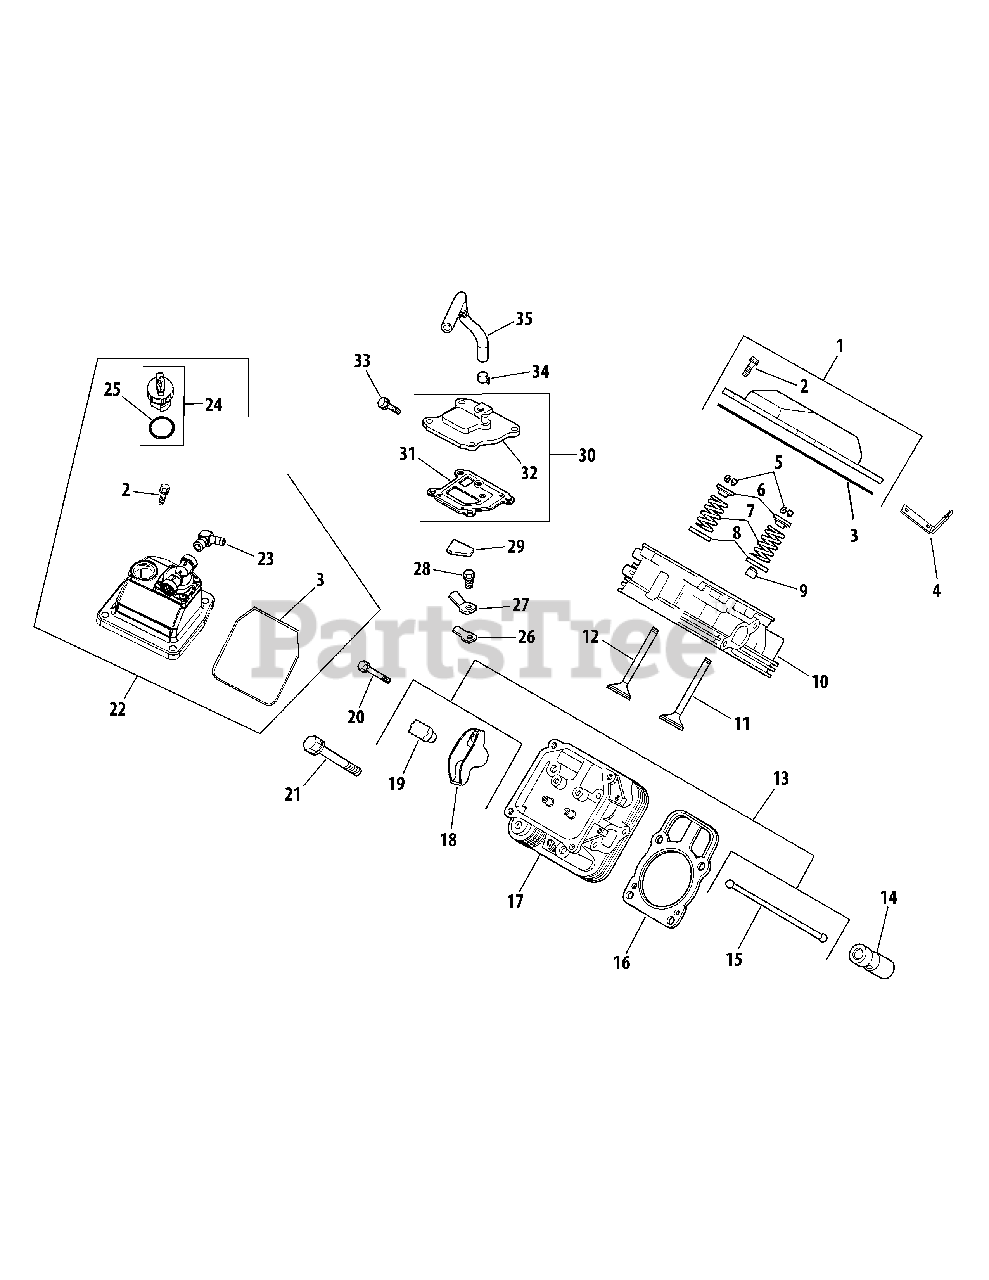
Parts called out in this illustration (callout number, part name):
1	Kit, Valve Cover (Includes 2-3)
2	Screw, Hex Flng, M6 x1.0 x 30
3	O-Ring, Valve Cover
4	Strap, Lifting
5	Kit, Retainer
6	Cap, Valve Spring
7	Spring, Valve
8	Retainer, Spring
9	Seal, Valve Stem
10	Head Assembly, #1 Cylinder
11	Valve, Intake Std
12	Valve, Exhaust Std
13	Kit, Valve Train (Incl. 15,18,19)
14	Lifter, Valve
16	Kit, Cyl. Hd. Gasket (Includes 21)
17	Head Assembly, #2 Cylinder
19	Pivot, Rocker Arm
20	Screw, Hex Flng, M6 x 1.0 x 34
21	Screw, Hex Flng, M10 x 1.5 x 90
22	Kit, Fuel Pump Valve Cover
23	Fitting, 90°
24	Cap Assembly, Oil Fill (Incl. 26)
25	O-Ring
26	Reed, Breather
27	Retainer, Breather Reed
28	Screw, Hex Flng, M5 x 0.8 x 10
29	Filter, Breather
30	Kit, Breather (Includes 32-34)
31	Gasket, Breather
32	Cover, Breather
33	Screw, Hex Flng M6 x 1.0 x 20
34	Clamp, Breather
35	Hose, Breather
